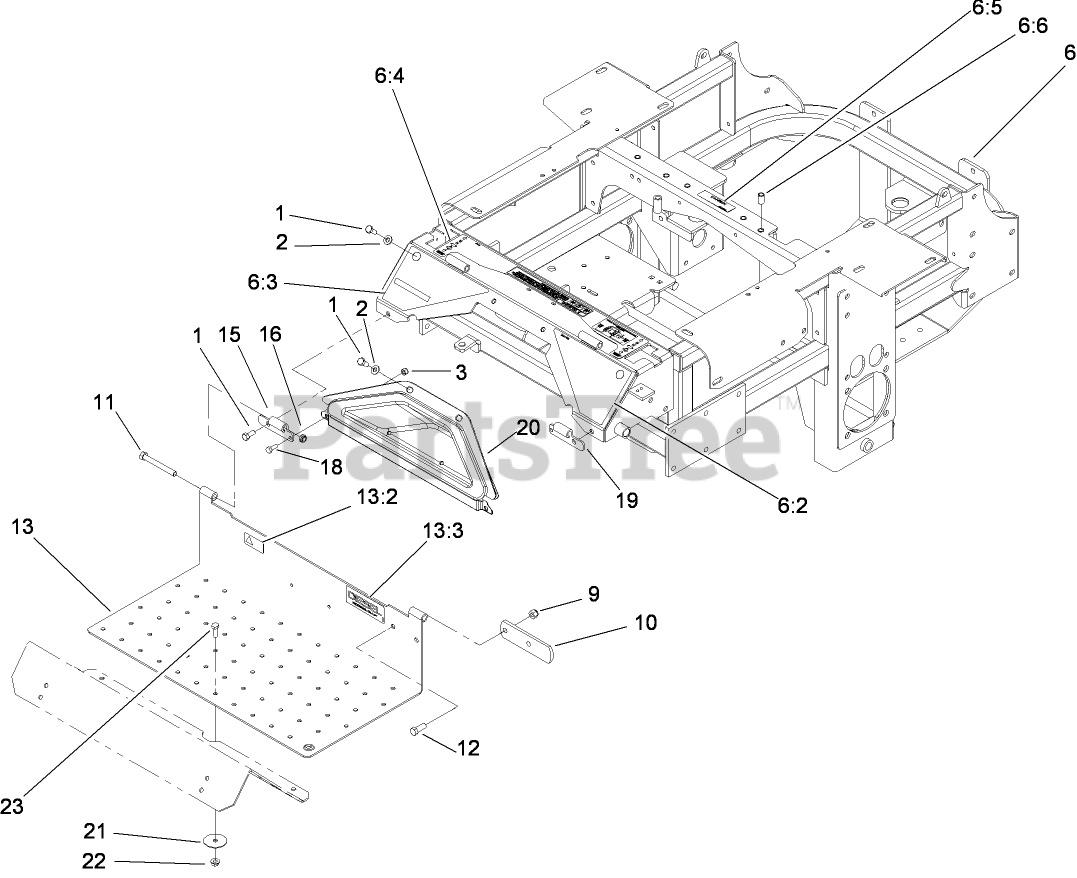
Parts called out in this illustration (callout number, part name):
1	SCREW-HH
2	WASHER-FLAT
3	NUT-LOCK, NI
6	TRACTION FRAME ASM
6:2	DECAL-DANGER, LEFT
6:3	DECAL-WARNING, RIGHT
6:4	DECAL-CONSOLE, TOP (CE)
6:5	DECAL-WARNING
6:6	INSERT-THREADED
9	NUT-LOCK, NI
10	STOP-BRAKE, PARK
11	SCREW-HH
12	SCREW-HH
13	FLOOR PAN ASM
13:2	DECAL-PROTECTION, EAR
13:3	DECAL-DIESEL, BIO-READY
15	Hinge-Floorpan, LH
16	NUT-LOCK, NI
18	SCREW-HH
19	Hinge-Floorpan, RH
20	Pocket
21	WASHER
22	NUT-HF
23	SCREW-HH
